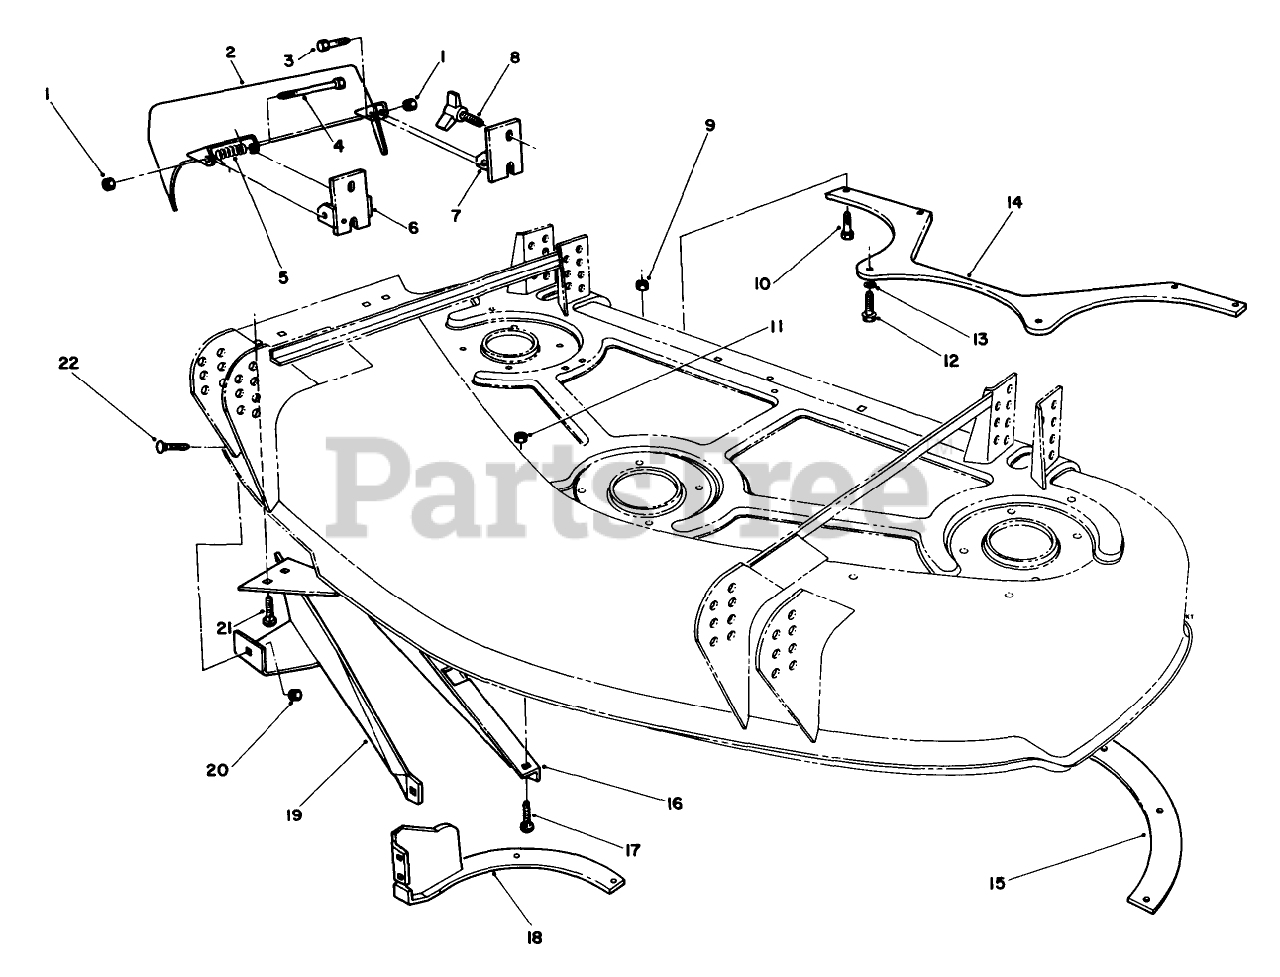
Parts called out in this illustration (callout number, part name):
1	NUT-HEX
2	Deflector-Grass
3	SCREW-HH
4	SCREW-HH
5	SPRING
6	Bracket-Pivot RH
7	Bracket-Pivot LH
9	NUT-LOCK, NI
10	SCREW-HH
11	NUT-KEPS
12	Screw
13	WASHER-FLAT
14	Baffle Bagging
15	RING - LH BAGGING R
16	Baffle-Rear
17	SCREW-CARR
18	Ring-Bagging RH
19	Baffle-Front
20	NUT-KEPS
21	BOLT-CARR
22	SCREW-CARRIAGE
